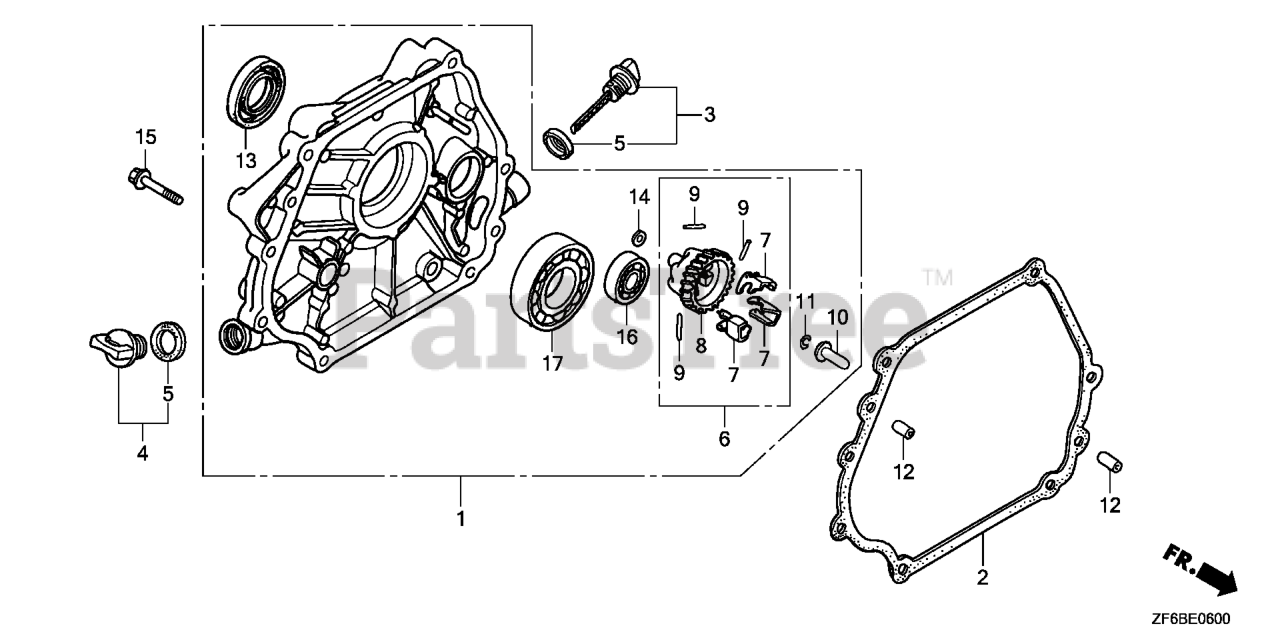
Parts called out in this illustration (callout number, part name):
1	COVER ASSY., CRANKCASE
2	GASKET, CRANKCASE COVER
3	CAP ASSY., OIL FILLER
4	CAP ASSY., OIL FILLER
5	GASKET, OIL FILLER CAP
6	GOVERNOR ASSY.
7	WEIGHT, GOVERNOR
8	HOLDER, GOVERNOR WEIGHT
9	PIN, GOVERNOR WEIGHT
10	SLIDER, GOVERNOR
11	CLIP, GOVERNOR HOLDER
12	PIN, DOWEL (8X12)
13	OIL SEAL (35X52X8)
14	WASHER, PLAIN (6MM)
15	BOLT, FLANGE (8X40) Use up to Engine SN 1003236.
16	BEARING, RADIAL BALL (6202)
17	BEARING, RADIAL BALL (6207)
